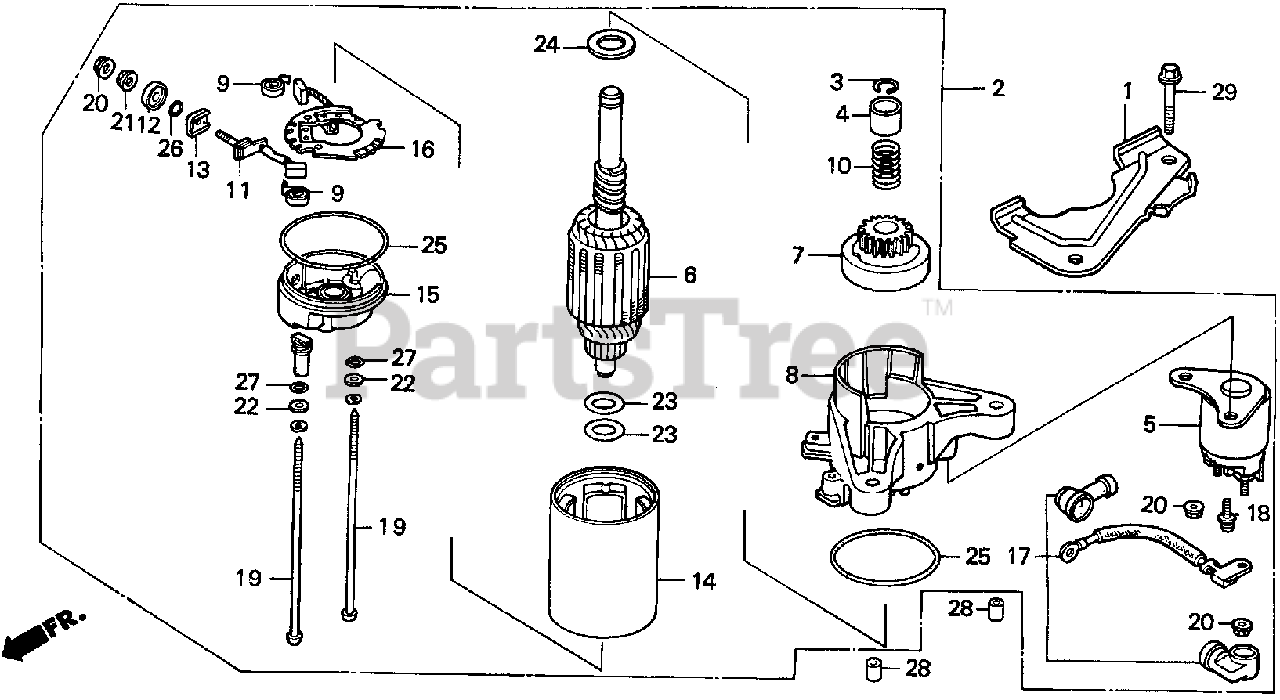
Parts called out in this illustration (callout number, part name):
1	PLATE, SIDE
2	STARTER MOTOR ASSY.
3	RING, SNAP
4	COLLAR, CLUTCH STOP
5	CONTACTOR ASSY.
7	CLUTCH ASSY., OVERRUNNING
8	HOUSING, DRIVE SIDE
9	SPRING, BRUSH
12	BUSH, INSULATION
13	BUSH, INSULATION
15	FRAME, STARTER END
16	PLATE, BRUSH HOLDER
17	WIRE, WATER COVER
18	SCREW-WASHER (5X14)
19	BOLT, THROUGH (NOT AVAILABLE)
19	BOLT, THROUGH
22	WASHER, STEEL PLATE (NOT AVAILABLE)
25	O-RING
27	O-RING
28	PIN, DOWEL (10X16)
29	BOLT, FLANGE (8X35)
